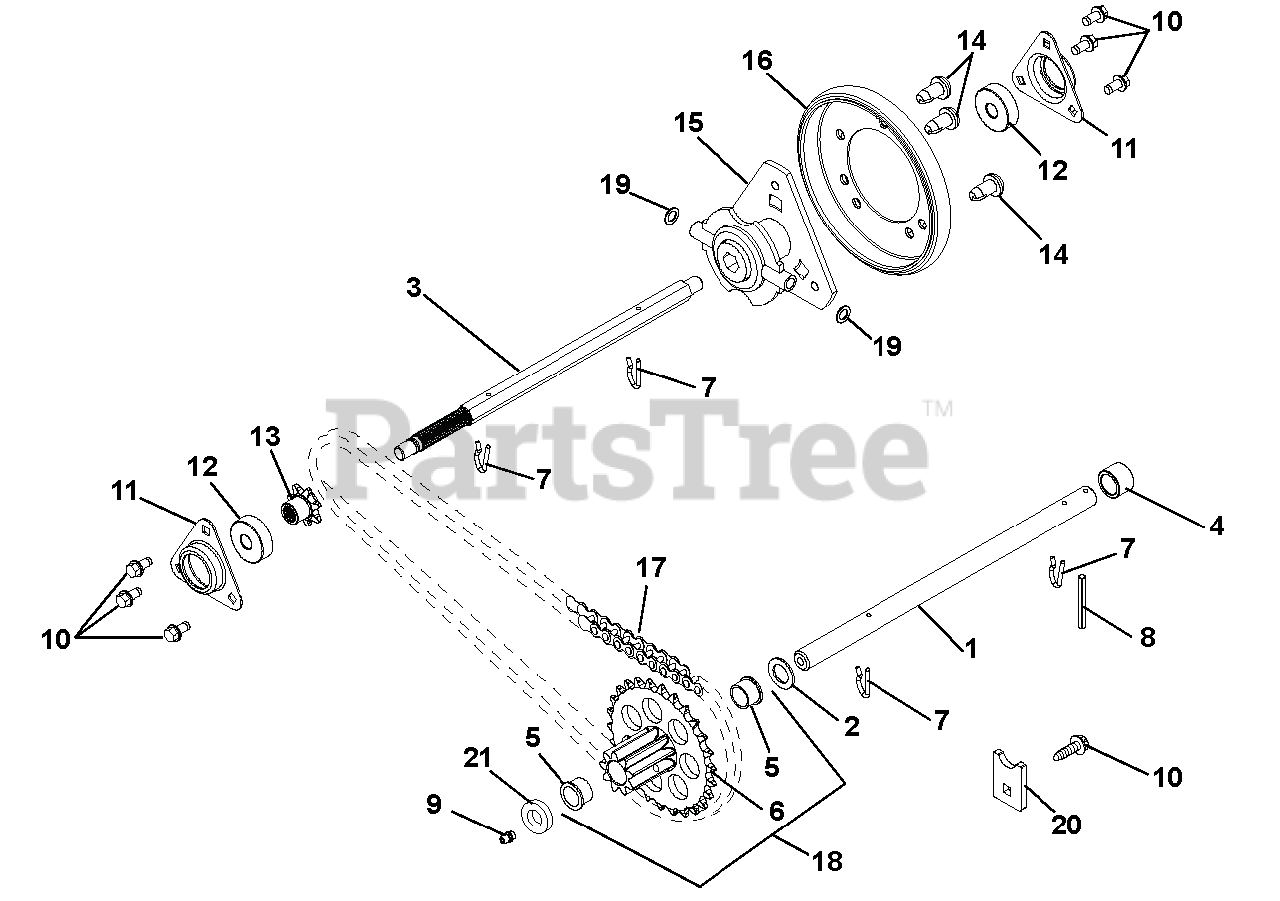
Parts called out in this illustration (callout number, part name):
1	SHAFT, PINION - HARDENED
2	WSHR-FL-STL .630X1.005X.062 YZ
3	SHAFT, HEX-W/SPLINE TRACK
4	SPACER, .635X.880X.611
5	BSHG-FLG .625X.750X.500X.875
6	PINION & SPROCKET
7	PIN, SPRING CLIP
8	@PIN-GRV .125X1.00 TP E ALLOY
9	ZERK,FITTING .25X.125 DRIVE IN
10	SCR-TAP .25-20X.50 HWH TR YWZ
11	FLANGE, BEARING
12	BRG-BALL .437X1.375X.437
13	SPROCKET, PINION 7T W/SPLINE
14	SCR-TAP SERRDHDTX .31-18X.50BP
15	CARRIER, DRIVE DISK
16	FRICTION, DISC
17	CHAIN - #41, 32 PITCHES
18	PINION & SPROCKET W/BUSHINGS
19	WSHR-FL-STL .505X1.00X.062YWZC
20	TAB, ANTI ROTATION
21	BSHG-SLV, .635X.880X.305
